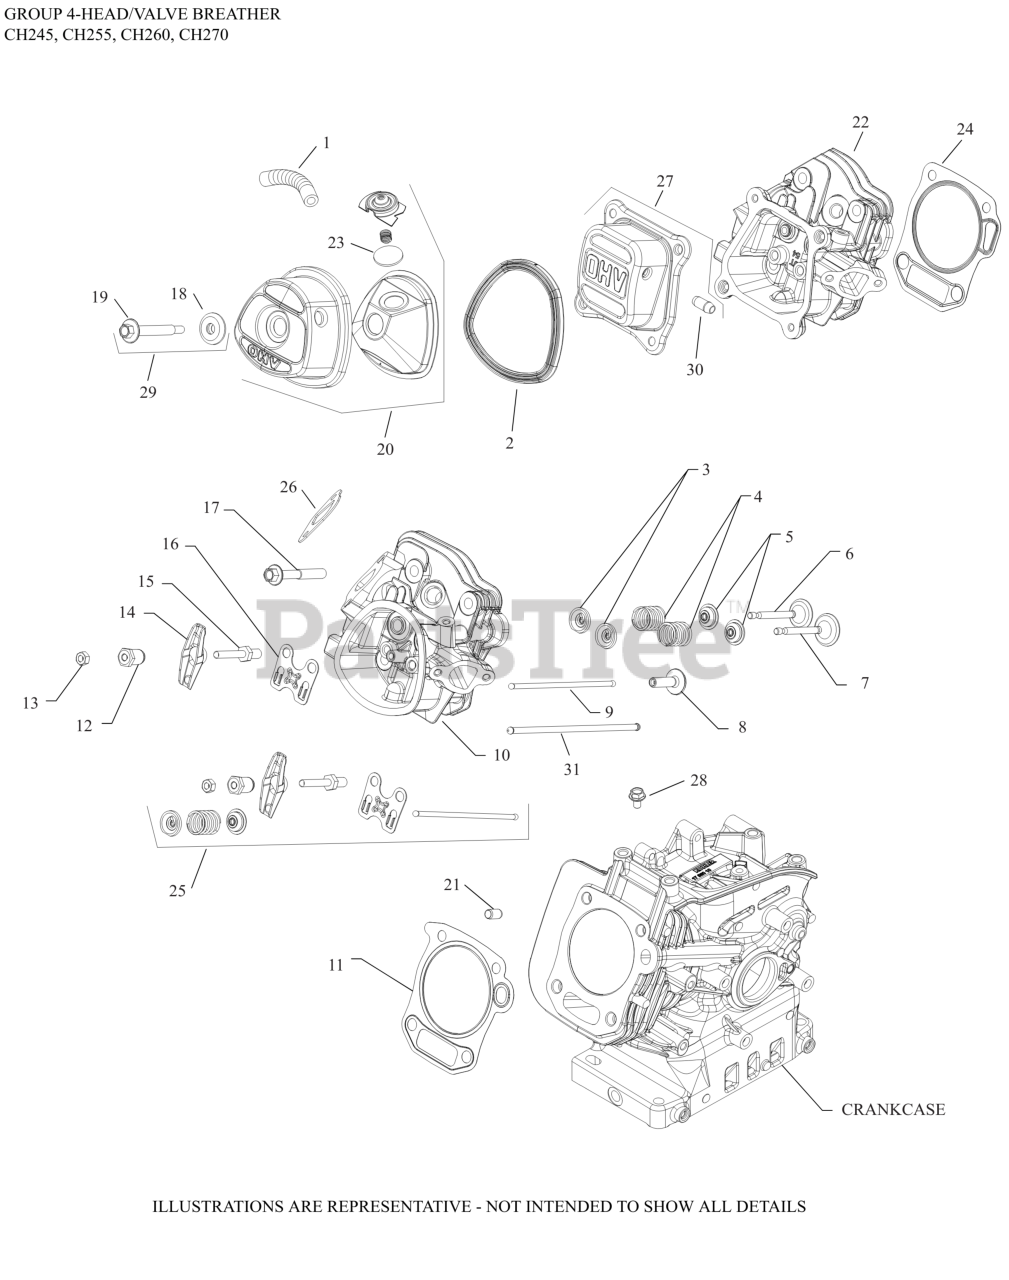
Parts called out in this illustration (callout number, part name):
1	TUBE, BREATHER
3	RETAINER, VALVE SPRING
4	SPRING, VALVE
5	SEAL, VALVE
6	VALVE, EXHAUST
7	VALVE, INTAKE
9	ROD, PUSH
12	PIVOT, ROCKER ARM
13	NUT, HEX JAM
14	ARM, ROCKER
15	STUD, ROCKER ARM-USE 14 072 22-S
16	PLATE, PUSHROD GUIDE
17	SCREW, HEX FLANGE CYL HEAD
22	CYLINDER HEAD
23	REED, BREATHER
24	GASKET, CYLINDER HEAD
25	KIT, VALVE TRAIN
27	COVER, VALVE ASSEMBLY
